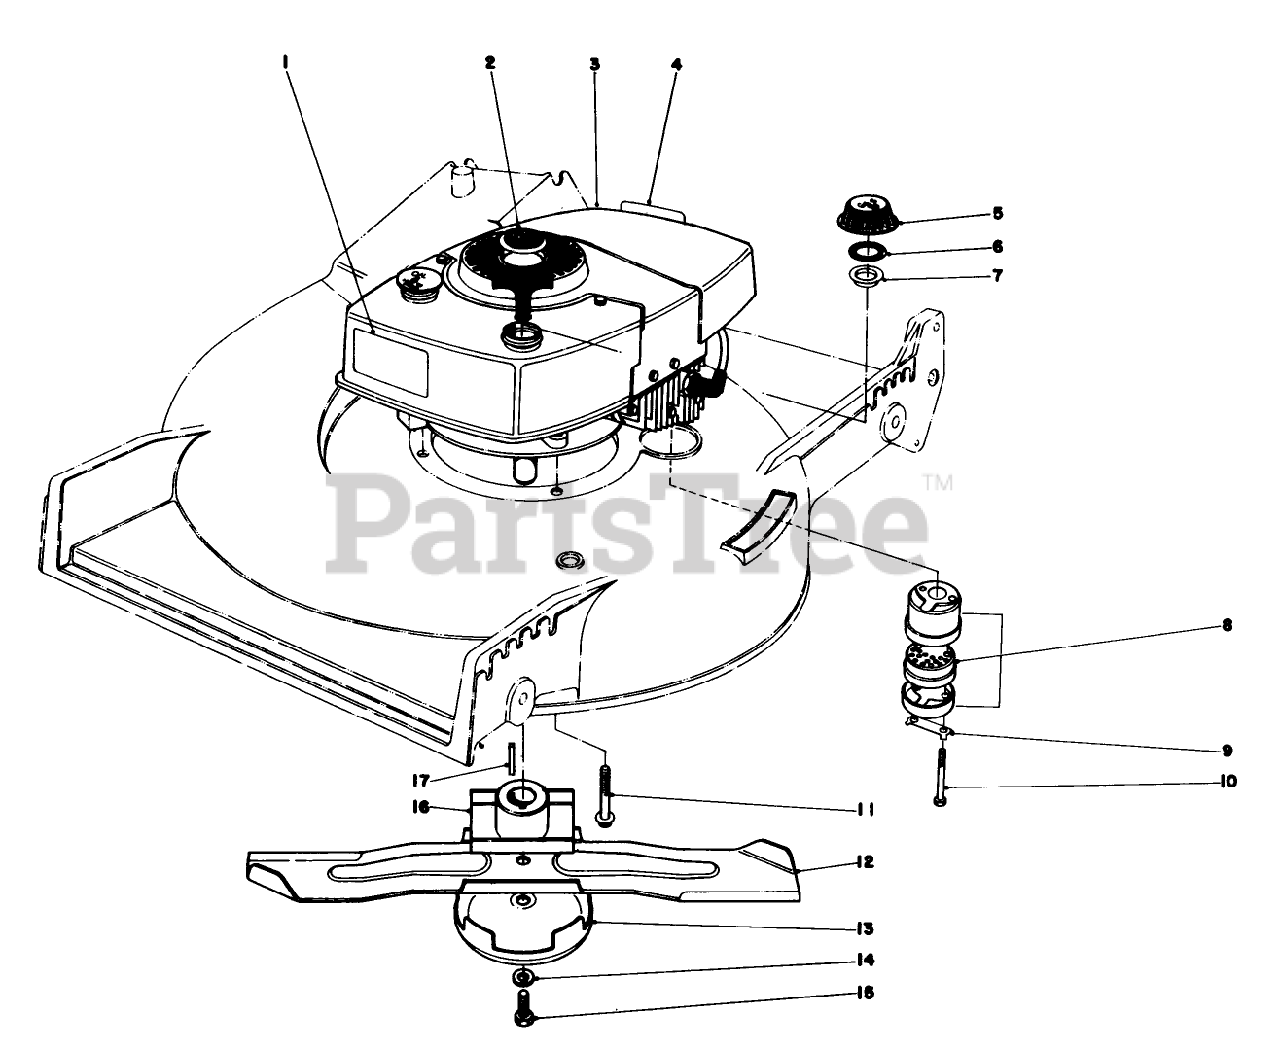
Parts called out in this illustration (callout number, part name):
1	Decal
2	PLUG BUTTON
3	Engine
4	Decal-Maintenan
5	Gas Cap (Incl. Ref. #6 & 7)
6	GASKET
7	GAS CAP BAFFLE
8	Muffler Assy. (Incl .Ref . #9 & 10)
9	CLIP - LOCKING
10	SCREW-HH
11	SCREW-HWHTF
12	Blade
13	AntiScalp Cup
14	WASHER-LOCK
15	BLADE SCREW
16	BLADE RETAINER WA(BLACK)
17	KEY-SQUARE
